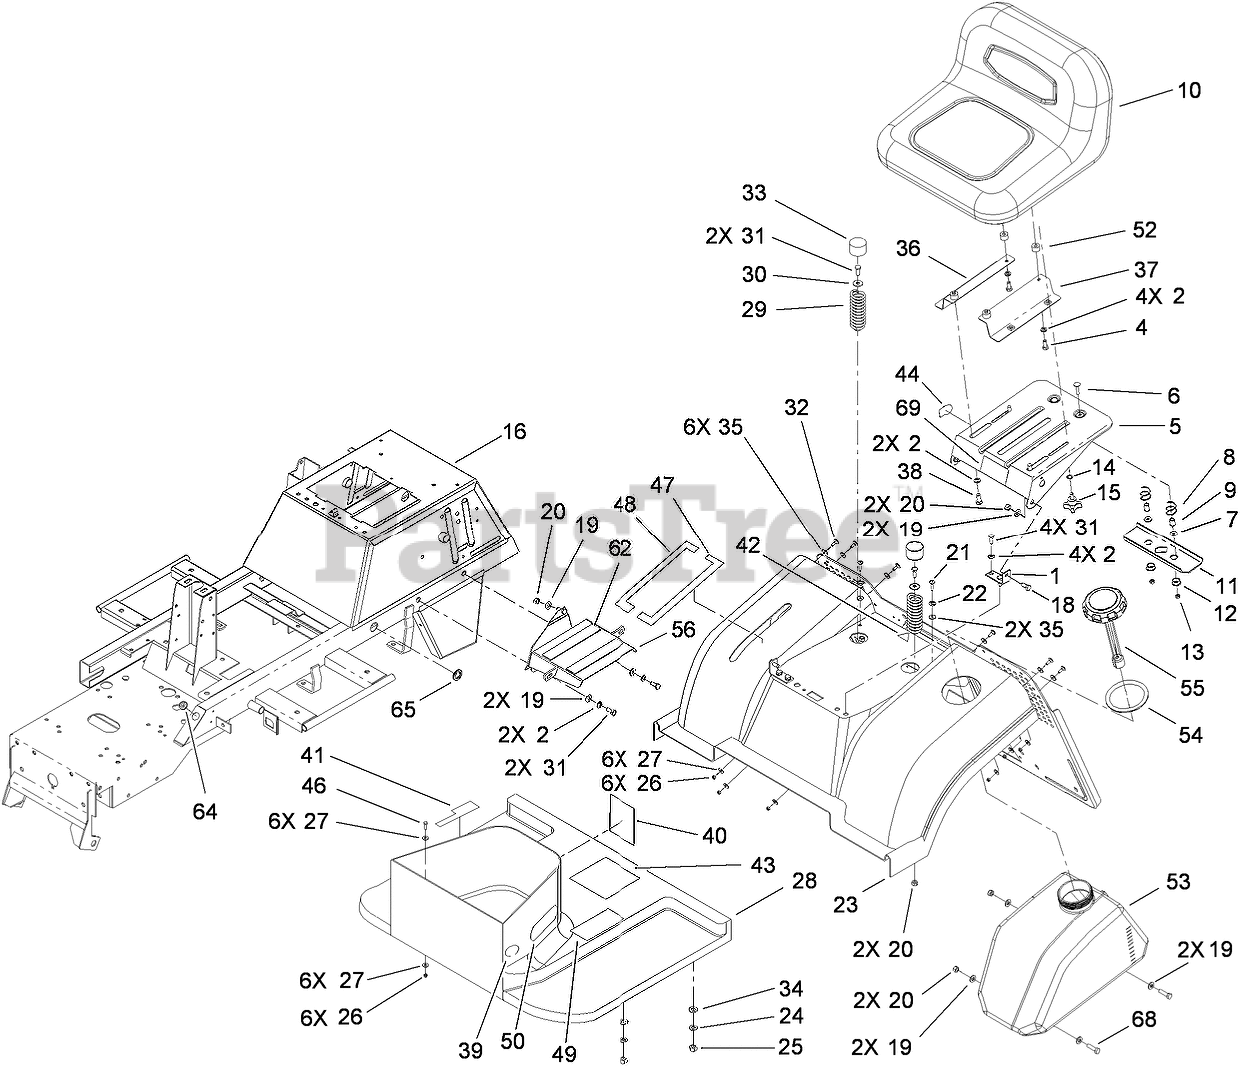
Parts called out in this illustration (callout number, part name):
1	BRACKET-SUPPORT, SEAT
2	WASHER-LOCK
4	SCREW-HH
5	SUPPORT-SEAT
6	BOLT-CARRIAGE
7	WASHER-FLAT
8	SPRING-SEAT
9	SPACER-SPLIT
10	SEAT ASM
11	BRACKET
12	BUSHING
13	NUT-LOCK
14	WASHER-SPRING
15	KNOB-ADJUSTMENT
16	CHASSIS-FRAME
18	SCREW-SUPPORT, SEAT
19	WASHER-PLAIN
20	NUT-LOCK, NI
21	SCREW-HSFH
22	WASHER-FINISH
23	FENDER-BODY, REAR
24	WASHER-FLAT
25	NUT-LOCK, NI
26	NUT-LOCK
27	WASHER-FLAT
28	FOOTREST ASM
29	SPRING-SEAT
30	WASHER-PLAIN
31	SCREW-HH
32	BOLT-CARRIAGE
33	CAP-HUB
34	WASHER-RUBBER
35	WASHER-RUBBER
36	BRACKET-SEAT, RH
37	BRACKET-SEAT, LH
38	Screw
39	DECAL-BRAKE, PARKING
40	DECAL-STARTING
41	DECAL-OPERATION, HYDRO
42	DECAL-BAG TO FRAME
43	DECAL-DANGER
44	DECAL-SWITCH
46	SCREW-HH
47	DECAL-HOC, LH
48	DECAL-HOC, RH
49	DECAL-OPERATION
50	DECAL-TOWER
52	SHIM-SEAT
53	TANK-FUEL
54	PROTECTOR-NECK, FILLER
55	CAP-FUEL
56	BRACKET-FUEL, TANK
62	STRIP-RUBBER, FUEL TANK
64	GROMMET
65	GROMMET
68	SCREW-HH
69	DECAL-DANGER
